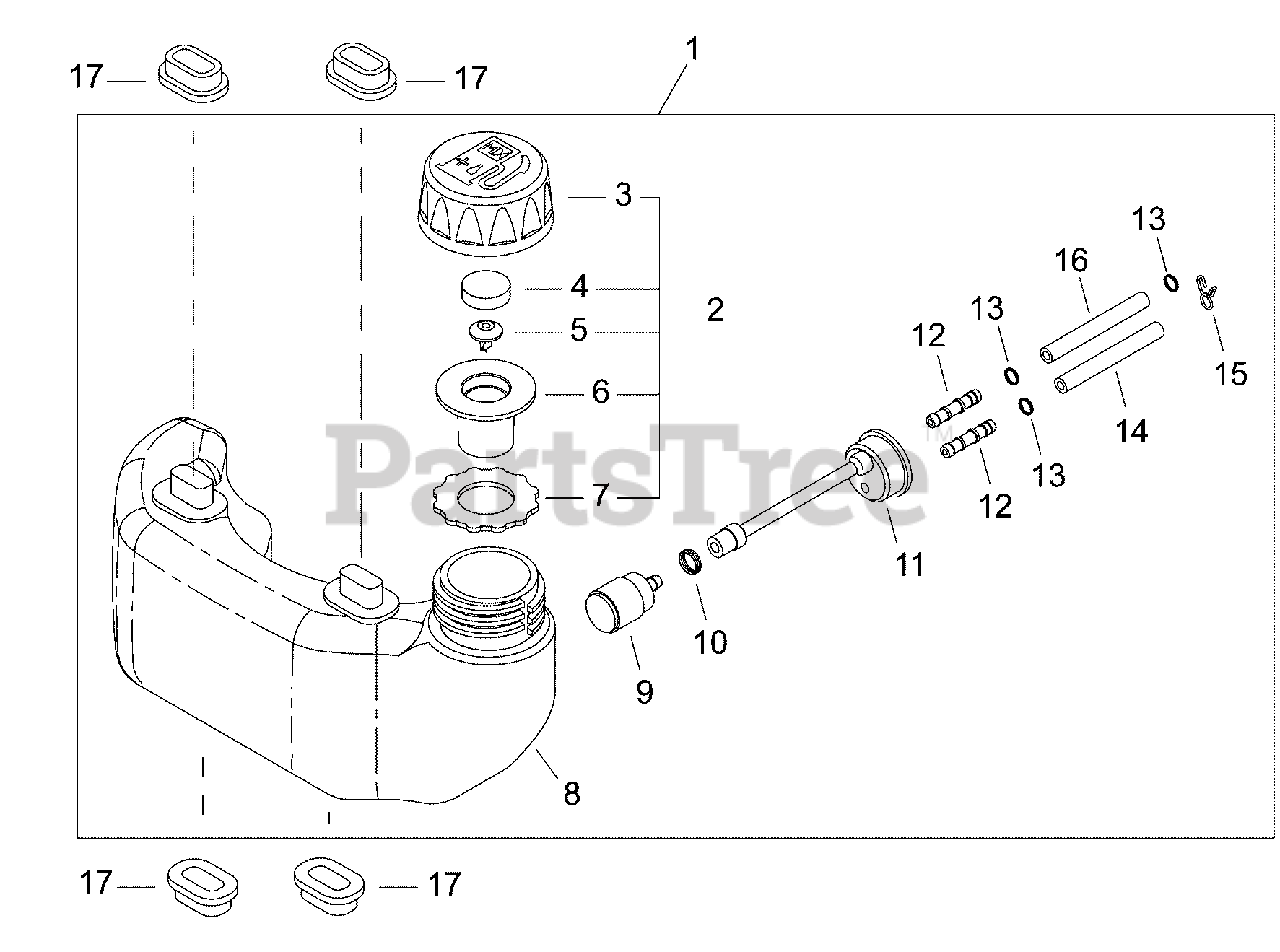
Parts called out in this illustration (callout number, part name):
1	FUEL TANK ASSY
2	CAP ASSY
3	CAP ASSY
4	COVER, VENT
5	VENT, FUEL TANK
6	HOLDER, VENT
7	GASKET, CAP
8	TANK, FUEL
9	FILTER, FUEL
10	RING, RETAINING
11	FUEL PIPE ASSY
12	CONNECTOR, PIPE
13	RING, RETAINING - 6
14	PIPE - RETURN
15	CLIP - SPRING
16	PIPE
17	CUSHION, FUEL TANK
